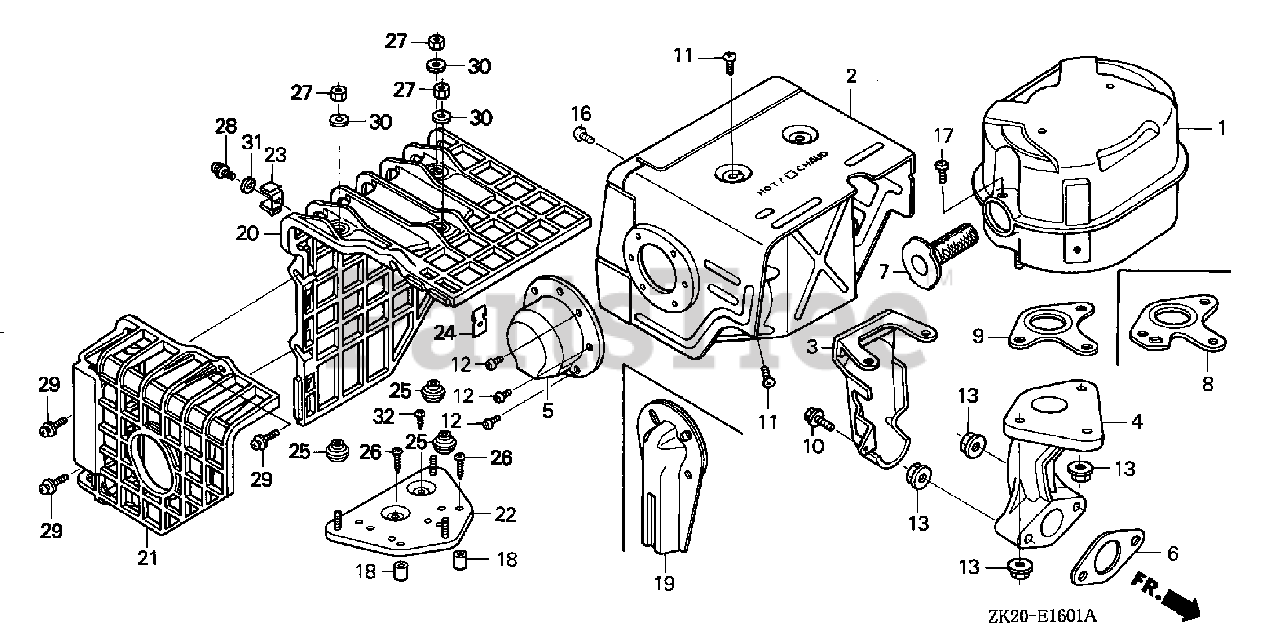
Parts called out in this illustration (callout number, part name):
1	MUFFLER
2	PROTECTOR, MUFFLER
4	PIPE, EX.
6	GASKET, EX. PIPE
6	GASKET, EX. PIPE (WACKER)
7	ARRESTER, SPARK
8	GASKET, MUFFLER (ARRESTER)
11	SCREW, TAPPING (5X8)
13	NUT, FLANGE (8MM)
17	SCREW, TAPPING (5X8)
